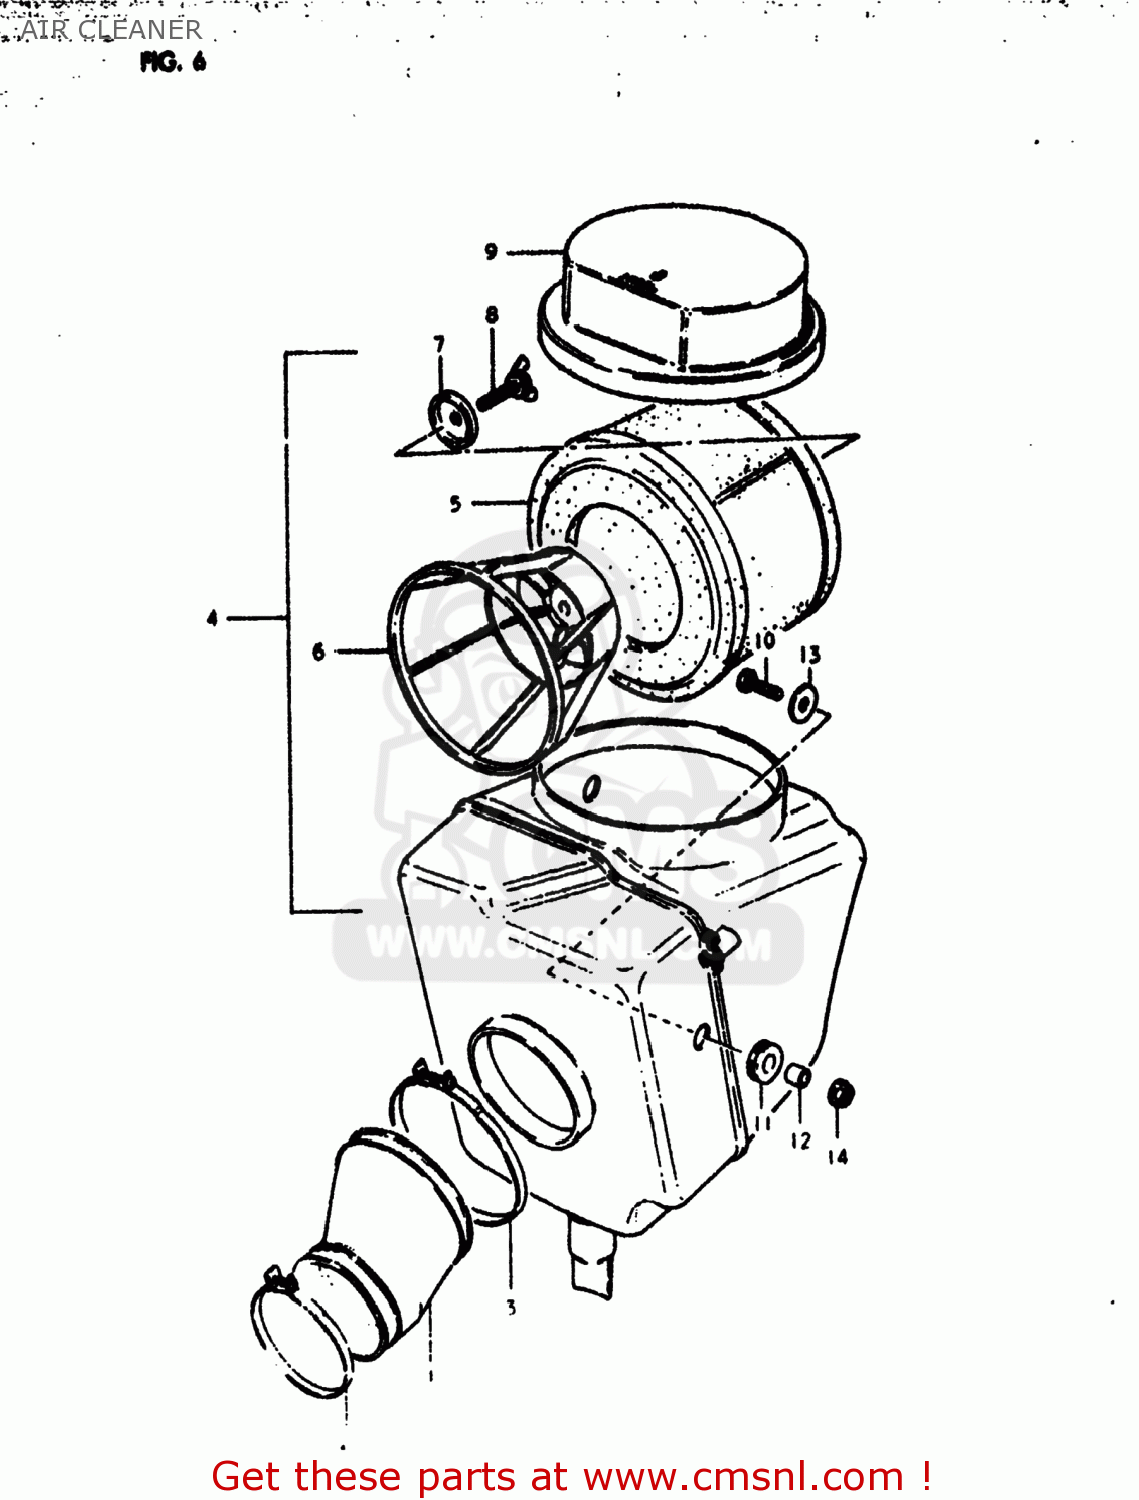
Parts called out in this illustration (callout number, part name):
1	TUBE,AIR CLEANER OUTLET
2	CLAMP
3	CLAMP
4	CLEANER ASSEMBLY,AIR
5	FILTER
6	HOLDER
7	HOLDER,FILTER
8	WING BOLT,AIR CLEANER
9	CAP,AIR CLEANER
10	BOLT
11	CUSHION
12	SPACER (6.1X9X9)
13	WASHER (6.5X20X1.2)
14	NUT
